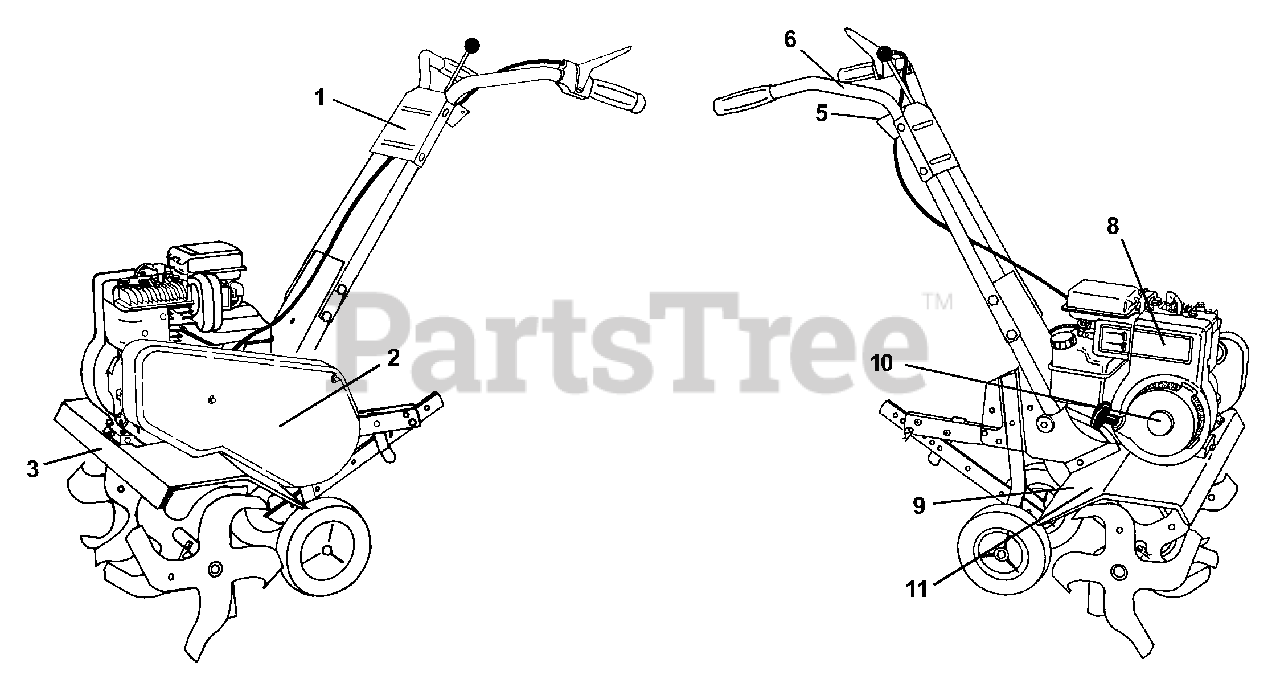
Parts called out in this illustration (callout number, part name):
1	Decal, Logo
2	Decal, Logo
3	Decal, Description
5	Decal, Reverse, Tine Control
6	Decal, Hand Placement
8	Decal, 5 HP
9	Decal, Warning, Rotating Tines
10	Decal, Recoil
11	Decal, Warning
